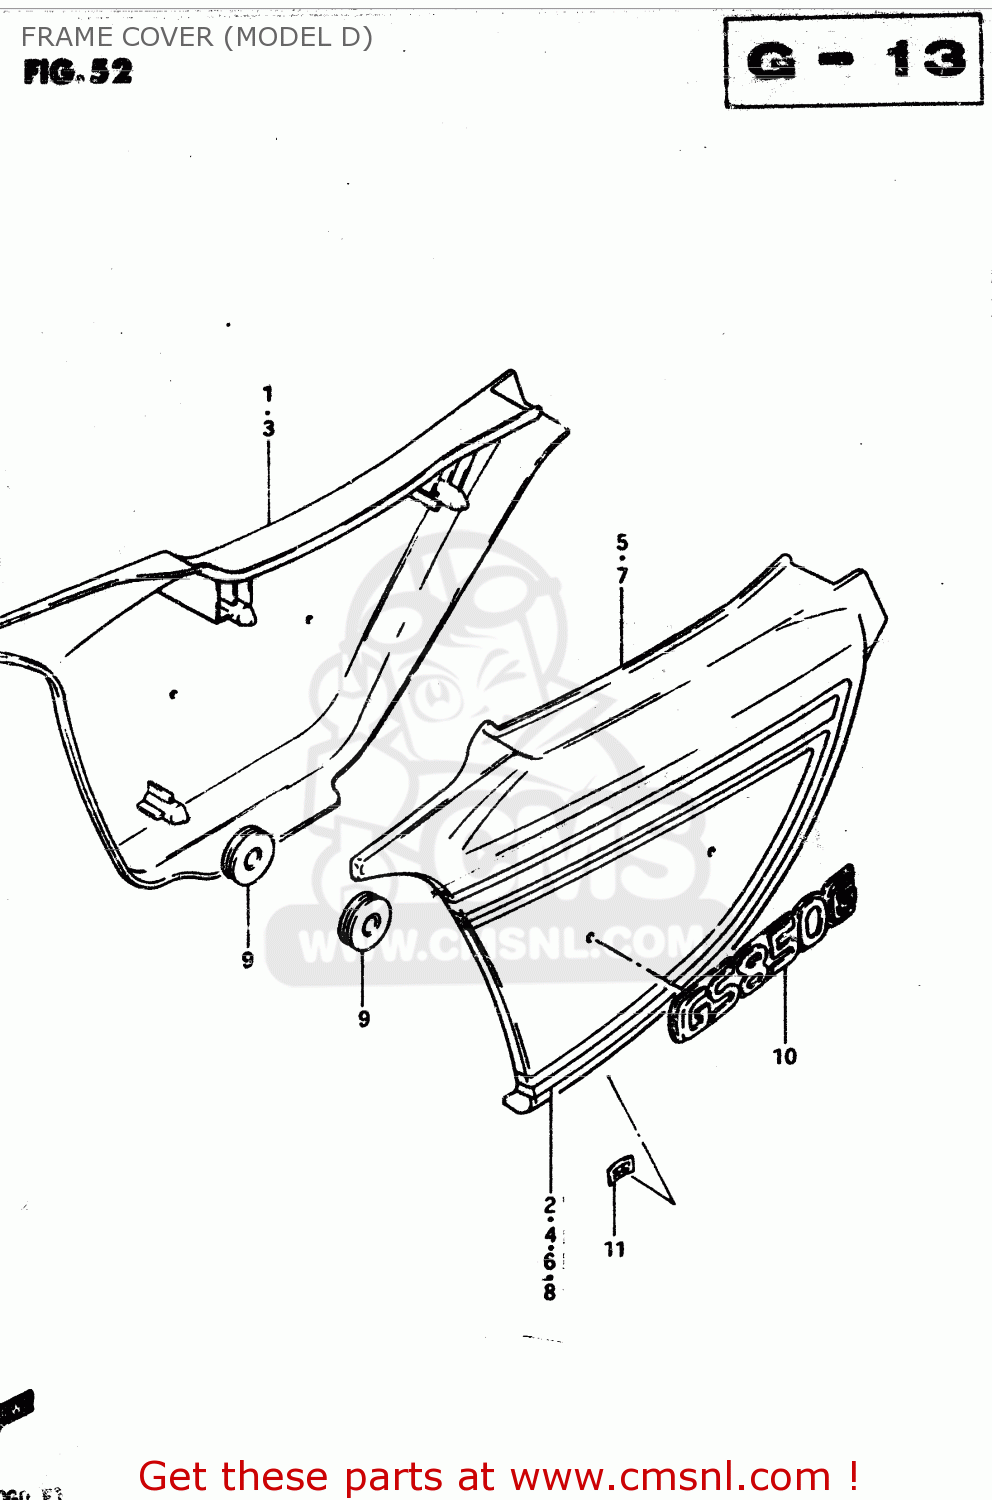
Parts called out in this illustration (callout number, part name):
1	COVER, FRAME RH (BLACK)
2	TAPE, RH
3	COVER, FRAME RH (WHITE)
4	TAPE, RH
5	COVER, FRAME LH (BLACK)
6	TAPE, LH
7	COVER, FRAME LH (WHITE)
8	TAPE, LH
9	CUSHION
10	EMBLEM,FRAME COVER
11	NUT
